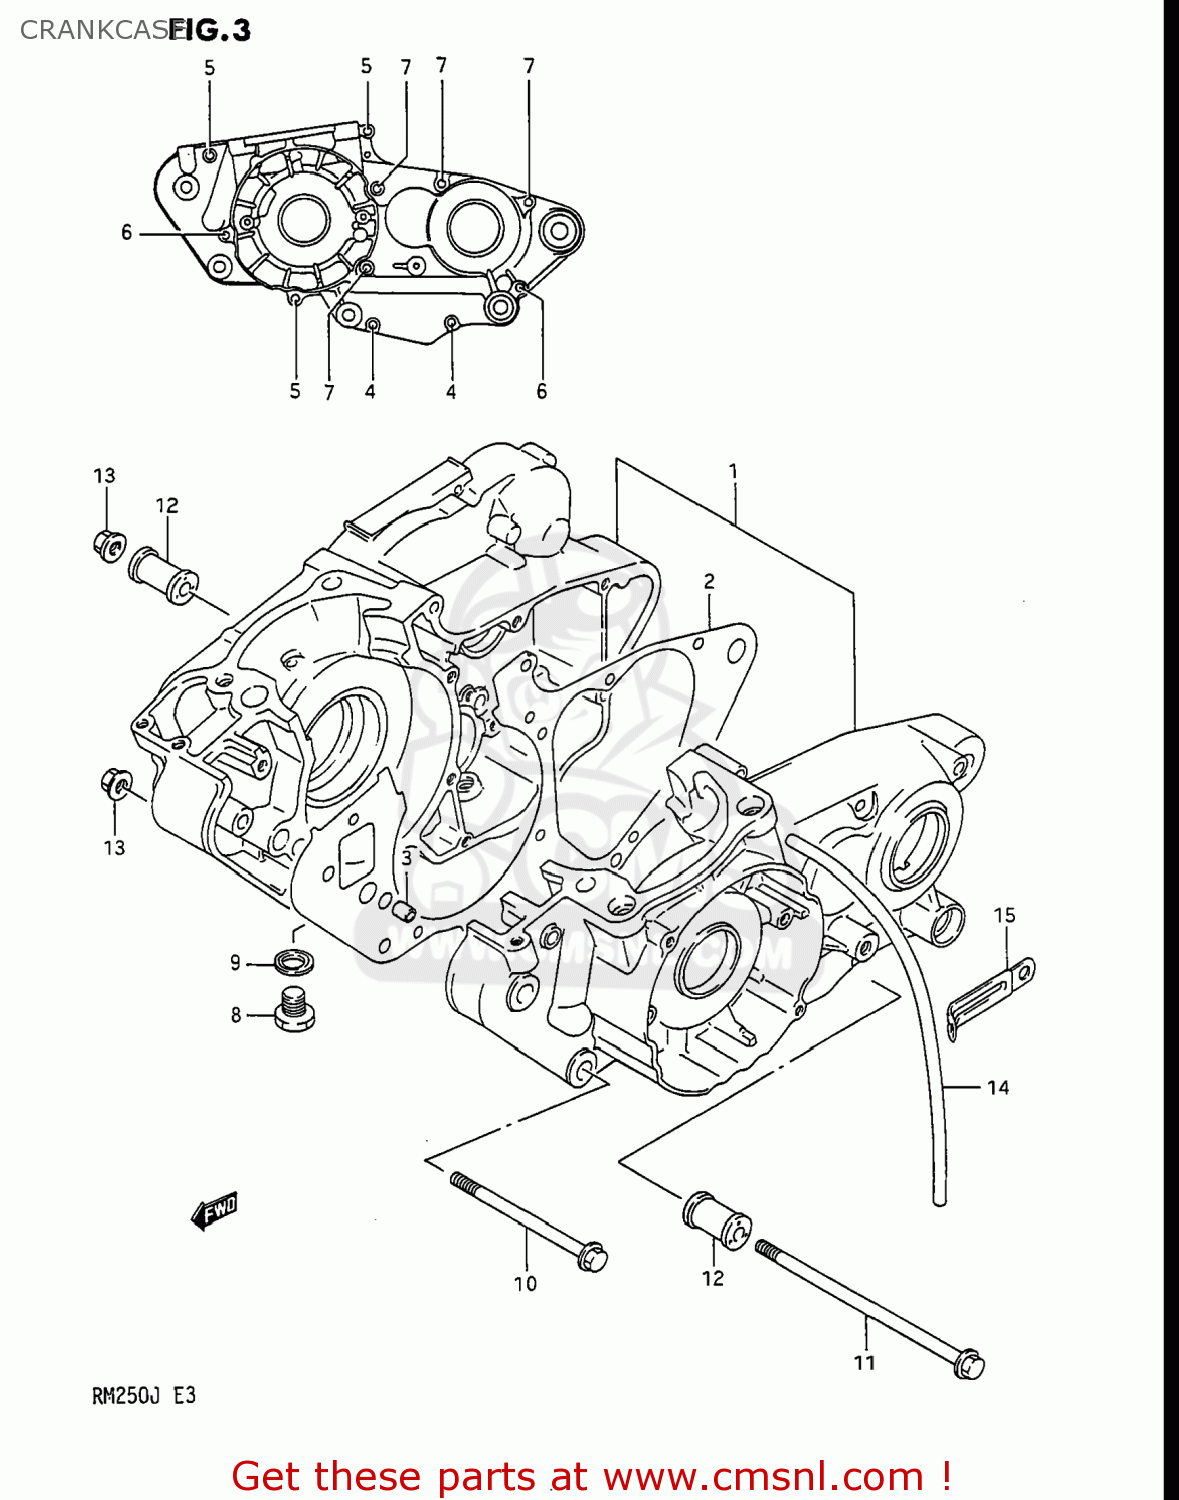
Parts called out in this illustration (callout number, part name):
1	CRANKCASE SET
2	GASKET,CRANKCASE (MCA)
3	PIN
4	SCREW
5	SCREW
6	SCREW
7	SCREW 6X60
8	PLUG
9	GASKET(14X19.2X2) (NAS)
10	BOLT(8X100)
11	BOLT
12	SPACER,ENGINE MOUNT(L:32)
13	NUT
14	HOSE
15	CLAMP
